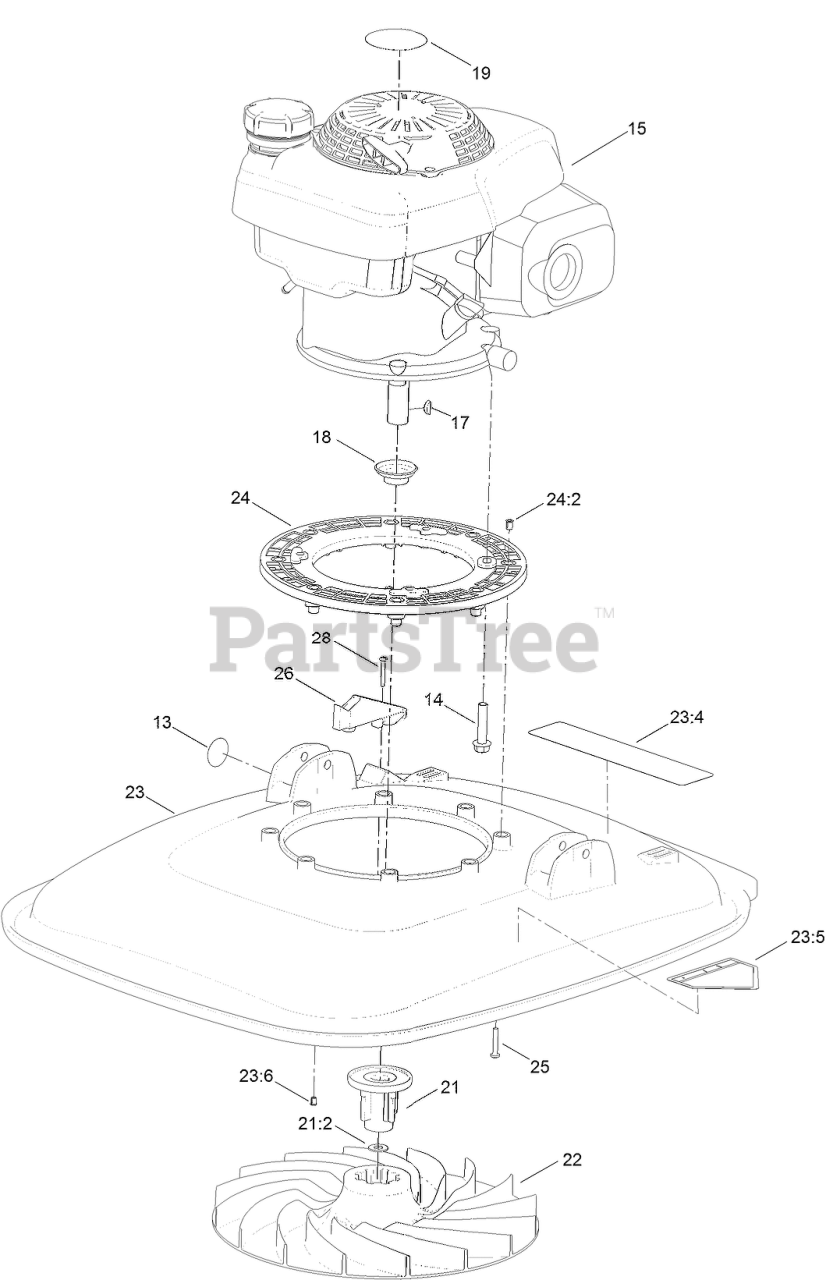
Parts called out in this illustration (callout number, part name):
13	DECAL
14	SCREW-TAPTITE
15	ENGINE-HONDA
17	KEY-WOODRUFF
18	PROTECTOR-SEAL, OIL
19	DECAL-ENGINE
21	DRIVE AND SPACER ASM
21:2	WASHER-PLAIN
22	IMPELLER
23	DECK ASM
23:4	DECAL-WARNING
23:5	DECAL-DANGER
23:6	INSERT
24	FRAME-ENGINE
24:2	INSERT-BRASS
25	SET-SCREW
26	BRACKET
28	SCREW
